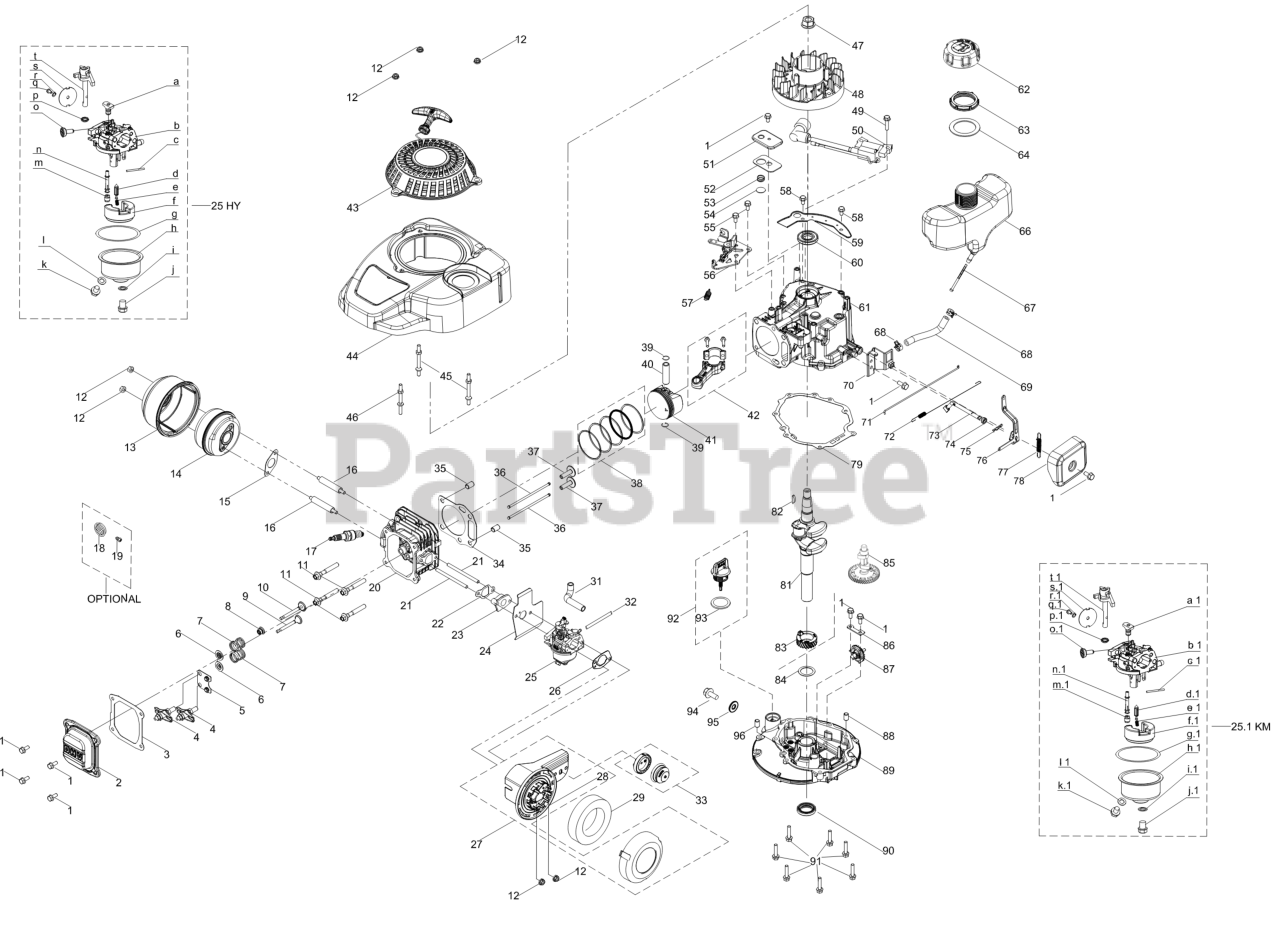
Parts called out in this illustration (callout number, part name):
1	BOLT M6-1 x 14 GR8.8
2	VALVE COVER
3	VALVE COVER GASKET
4	ROCKER ARM
5	PUSH ROD GUIDE
6	VALVE RETURN SPRING
7	VALVE SPRING
8	INTAKE VALVE SEAL
9	EXHAUST VALVE
10	INTAKE VALVE
11	SCREW M8 x 54 GR10
12	HEX NUT
13	MUFFLER SHIELD
14	MUFFLER ASSEMBLY
15	MUFFLER GASKET
16	STUD M6-1 x 76
17	SPARK PLUG (F5RTC/RN11YC4/BPR5ES)
18	SPARK ARRESTOR
19	SPARK ARRESTOR SCREW
20	CYLINDER HEAD
21	STUD M6 x 98
22	CARBURETOR INSULATOR GASKET
23	CARBURETOR INSULATOR
24	CARBURETOR GASKET
25	CARBURETOR
25.1	CARBURETOR
25HY	CARBURETOR
26	AIR FILTER BASE GASKET
27	AIR FILTER ASSEMBLY
28	AIR FILTER BASE
29	FOAM AIR FILTER
31	BREATHER HOSE
32	PRIMER HOSE
33	VENTED PRIMER ASSEMBLY
34	CYLINDER HEAD GASKET
35	PIN (10MMx16MM)
36	PUSH ROD
38	PISTON RING SET
39	WRIST PIN CLIP
40	PISTON PIN
41	PISTION
42	CONNECTING ROD ASSEMBLY
43	STARTER RECOIL ASSEMBLY
44	ENGINE SHROUD ASSEMBLY
45	STUD M6 x 75
46	STUD M6 x 73
47	FLYWHEEL NUT M14-1.5
48	FLYWHEEL
49	BOLT M6-1 x 25 GR8.8
50	IGNITION COIL ASSEMBLY
51	BREATHER COVER PLATE
52	BREATHER COVER GASKET
53	BREATHER VALVE SPRING
54	BREATHER VALVE
55	BOLT M6-1 x 12 GR8.8
56	ENGINE BRAKE ASSEMBLY
57	BRAKE SPRING
58	BOLT M6-1 x 10 GR8.8
59	SHROUD COVER PLATE
60	UPPER SEAL
61	CRANKCASE
62	FUEL CAP ASSEMBLY
63	FUEL TANK NUT
64	FUEL TANK GROMMET
66	FUEL TANK
67	FUEL FILTER
68	CARBURETOR HOSE CLAMP
69	FUEL HOSE
70	COMPONENT BRACKET
71	THROTTLE LINKAGE
72	THROTTLE LINKAGE SPRING
73	GOVERNOR ARM SHAFT
74	OIL SEAL
75	COTTER PIN
76	GOVERNOR ARM ASSEMBLY
77	GOVERNOR SPRING
78	GOVERNOR SHIELD
79	CRANKCASE COVER GASKET
81	CRANKSHAFT
82	WOODRUFF KEY
84	THRUST WASHER
85	CAMSHAFT
86	GOVERNOR GEAR MOUNTING PLATE
87	GEAR GOVERNOR
88	DOWEL PIN 7 X 14
89	CRANKCASE COVER
90	LOWER CRANKSHAFT SEAL
91	BOLT-M6-1 x 28 GR8.8
92	DIPSTICK ASSEMBLY
93	DIPSTICK O-RING
94	OIL DRAIN PLUG
95	FLAT WASHER
96	DOWEL PIN 9 X 14
